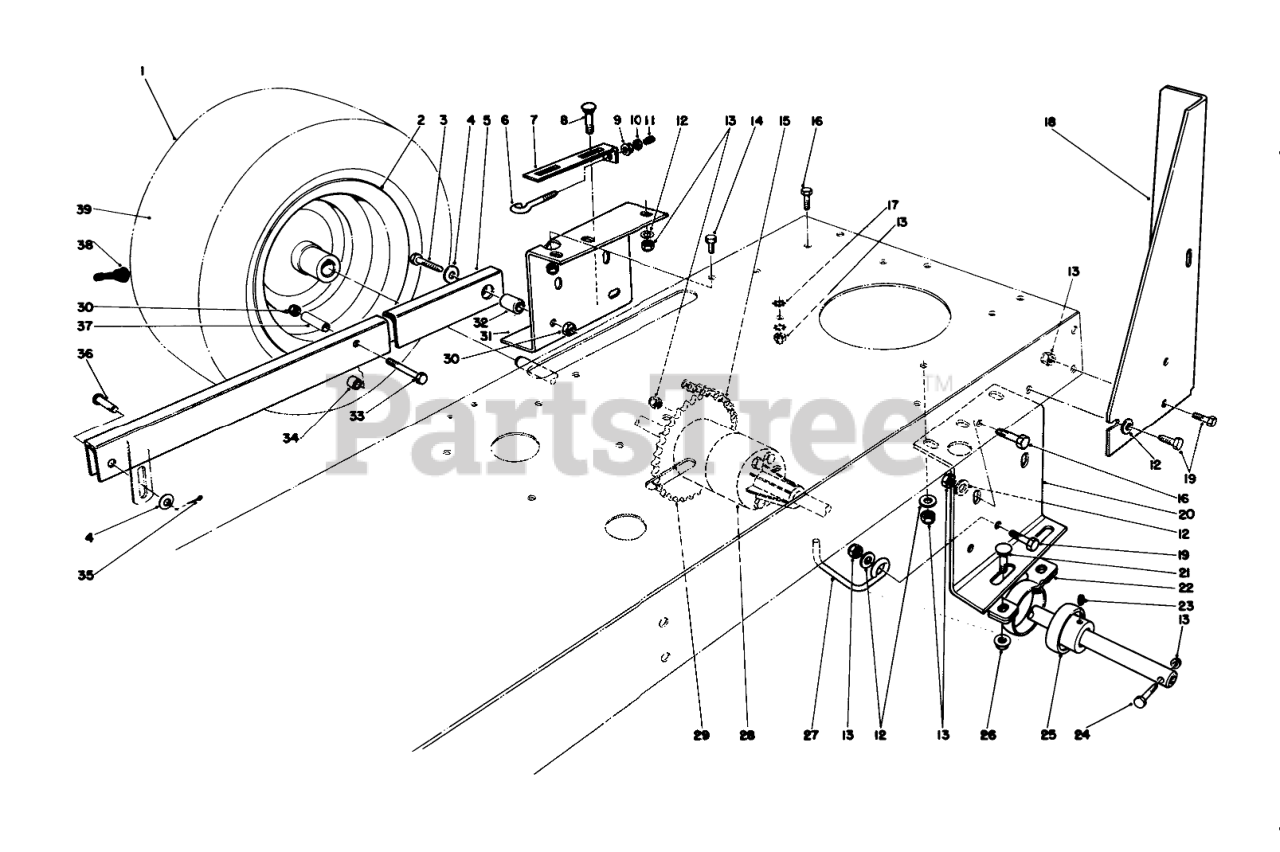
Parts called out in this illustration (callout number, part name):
3	SCREW-HH
4	WASHER-FLAT
5	REAR SUSP ARMR
6	SCREW-ADJUSTING
7	PLATE-ADJUSTING
8	BOLT-CARR
9	NUT-HF
10	NUT-HEX
11	VINYL ROD TIP
12	WASHER-PLAIN
13	NUT-LOCK, NI
14	SCREW-HH
15	ROLLER CHAIN
16	SCREW-HH
17	WASHER-LOCK, INTERNAL
18	LH STANDBAR B
19	SCREW-HH
20	LH REAR AXLE SUPT R
21	BOLT-CARR
22	RTNR-PILLOW BLK
23	SCREW-SET, HSH
24	AXLE MTG BOLT
25	Bearing-Ball (Incl. Ref. #23)
26	NUT-HF
27	BELT GUIDE
28	DIFFERENTIAL
29	42T DIFF SPROCKET
30	NUT-LOCK, CONE
31	RH AXLE SUPPORT R
32	PIN-SUPT ARM
33	SCREW-HH
34	INNER TUBE SPACER
35	PIN-COTTER
36	PIN-CLEVIS
37	OUTER TUBE SPACER
38	STEM-VALVE
39	TUBE-INNER
